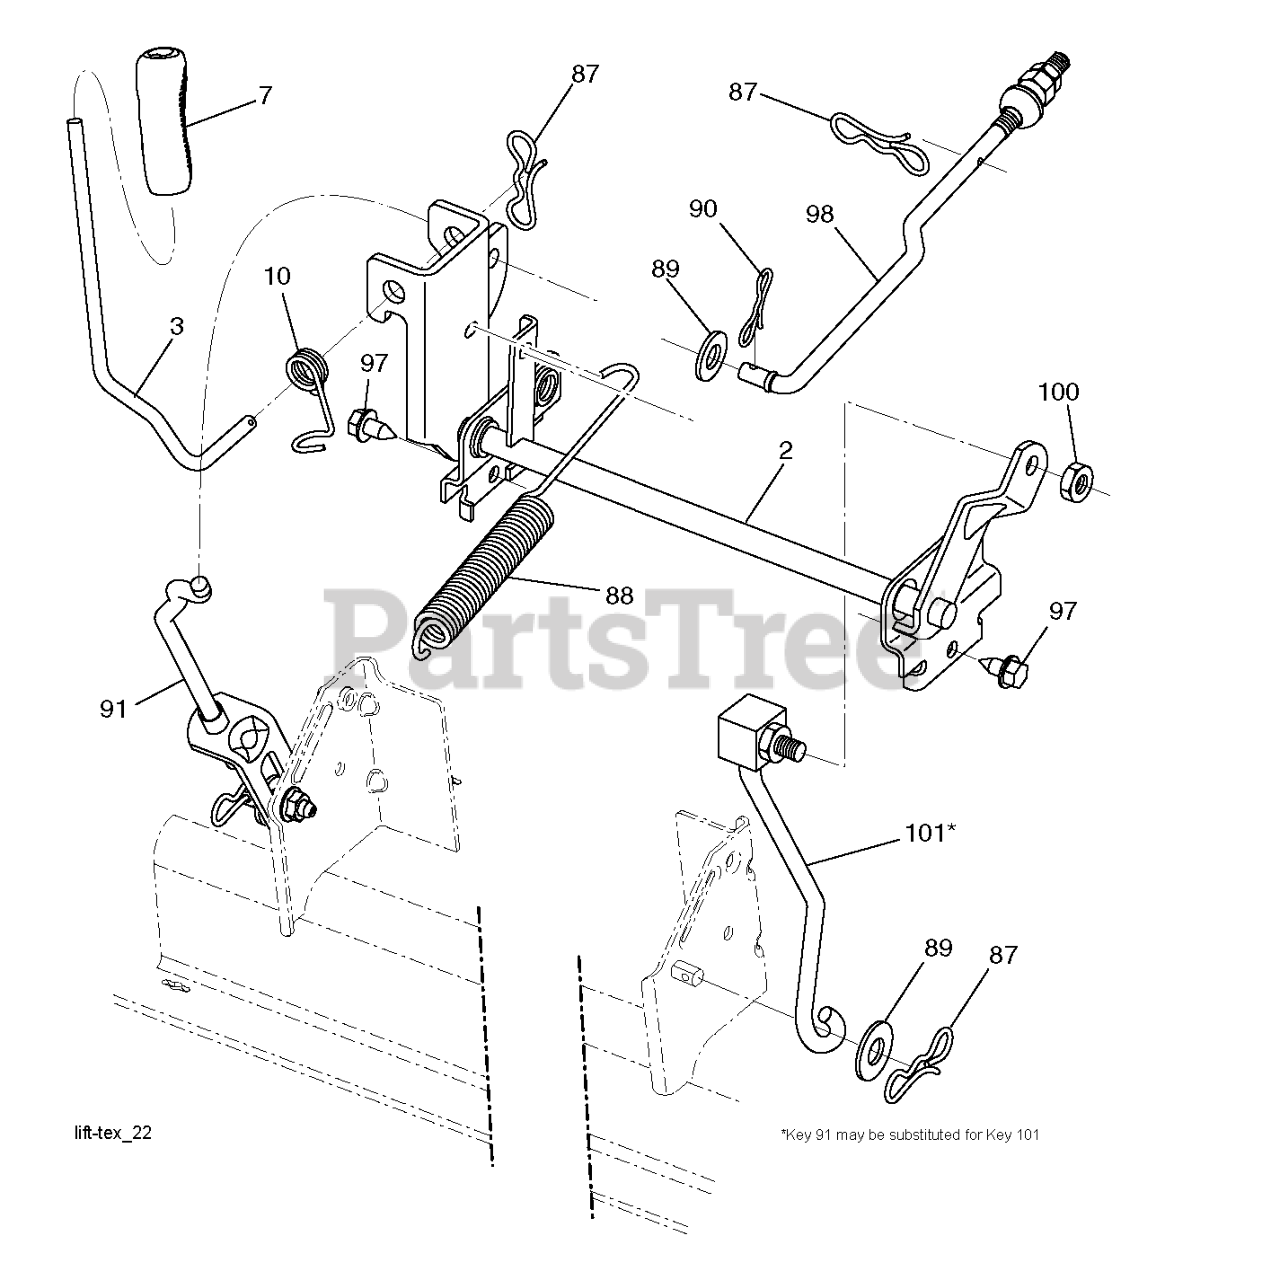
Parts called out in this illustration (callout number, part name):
2	SHAFT.ASM.CROSS.LIFT
3	LEVER.LIFT.HANDLE.LT
7	GRIP.HANDLE.LIFT.PVC.BLACK
10	SPRING.TORSION.LIFT.HANDLE
87	PIN.COTTER.7/16.BOW TI.
88	SPRING.LIFT.ASSIST
89	WASHER.CLEAR.ZINC
90	PIN.COTTER.5/16.BOW TI
91	LINK.ASM.LIFT.REAR
97	SCREW, 3/8-16X3/4
98	LINK.ASM.SUSP.FRONT.MW
100	LOCKNUT
101	LINK.ASM.LIFT.FIXE.38/42/46"
